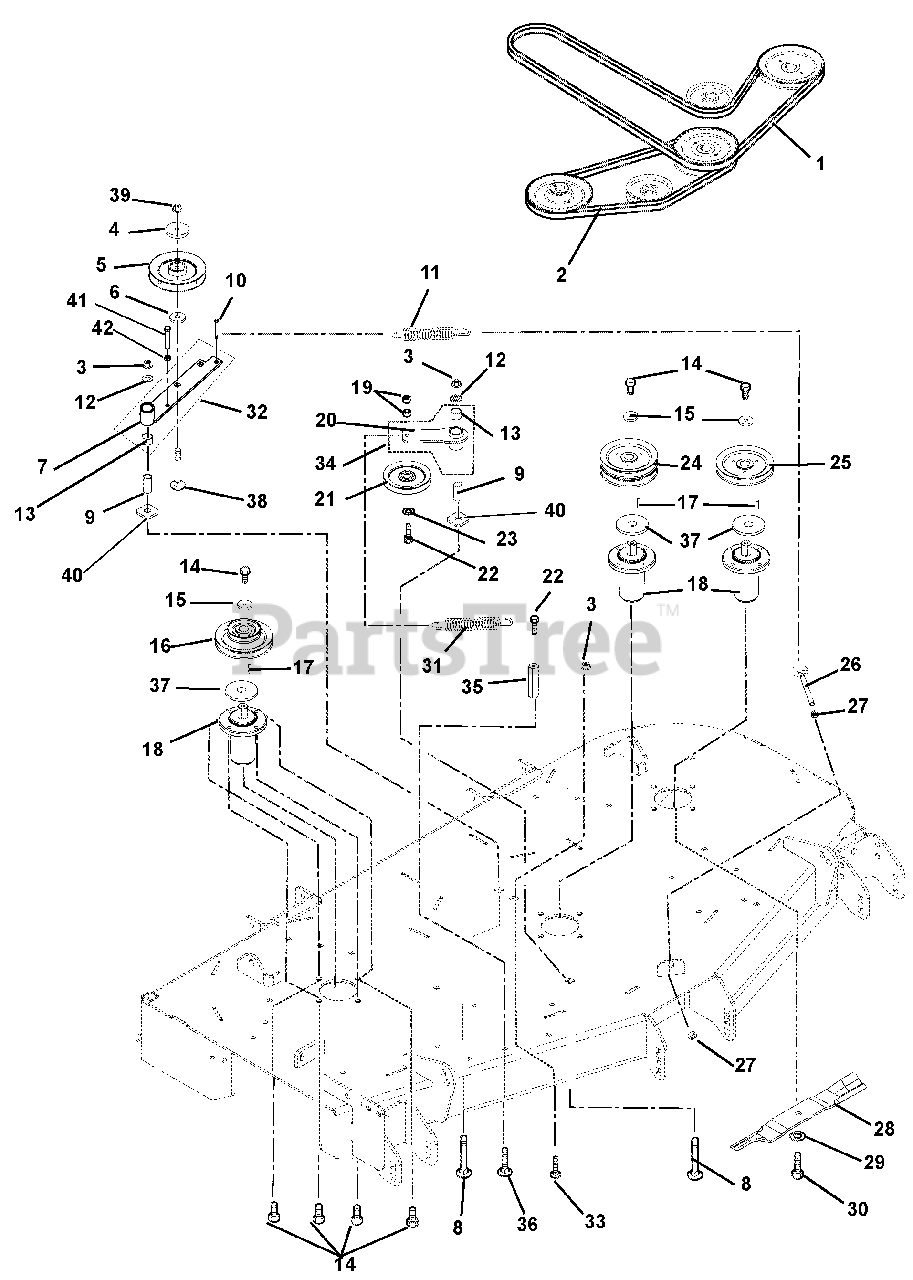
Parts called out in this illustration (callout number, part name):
1	Belt, 184.4" Long, PTO Drive Hex (992156)
2	V-Belt, 63" Long Cog B-Section (992156)
3	Nut, .50-13 Nyloc Flange
4	Cap, Idler Bearing Sealing
5	Pulley, V 6.0 x .500 ID Single Bearing
6	Bushing, Spacer .502 x .997 x .50
7	Weldment, Idler Arm
8	Bolt, Round Head Square Neck .50-13 x 3.50
9	Bushing, Spacer .505/.500 x .999/.996 x 2.05/2.03
10	Bolt, Shoulder EP .38-16 x .30 Hex
11	Spring, Extension (Deck Idler)
12	Washer, Flat Steel .531x 1.250 x.100
13	Bushing, 1.00 x 1.125 x 1.936
14	Bolt, Hex .38-16 x 1.00
15	Washer, Flat Steel .406 x 1.50 x .245
16	Sheave, Double, 1" ID x 6.75" x 4.35" OD (992156)
17	Key, Square .25 x .25 x 1 RC 40-50
18	Spindle Assembly
19	Nut, Locking Center .38-16
20	Weldment, Idler Arm
21	Assembly, V-Idler 5.00 O.D.
22	Bolt, Hex .38-16 x 2.25
23	Washer, Flat Steel .406 x .812 x .065
24	Sheave, Double 1" ID x 6.75" OD (992156)
25	Sheave, Single 1" ID x 6.75" OD (992156)
26	Bolt, .38-16 x 4.50 .62 Diameter Eye
27	Nut, Hex, Jam .375-16
28	Blade, Mower (20.50") (992156)
29	Washer, Bellville .63 x 1.625 x.14
30	Bolt, Hex .62-18 x 1.75 Grade 8
31	Spring, Extension
32	Assembly, PTO Idler Pivot Arm (Includes item # 7 and item # 13)
33	Bolt, Round Head Square Neck .50-13 x 1.5, Full Thread, Grade 5
34	Assembly, Idler Arm (Includes item # 13 and item # 20 )
35	Nut, Coupling .375-16 x 1.75
36	Bolt, Round Head Square Neck .38-16 x 1.00
37	Retainer, Grease
38	Bolt, Round Head Square Neck .50-13 x 3.00 Grade 5
39	Nut .50-13 Nyloc Flange
40	Washer, Flat .640 x 1.75 x .250
41	Bolt, Hex .38-16 x 2.75
42	Nut, Hex .38-16
